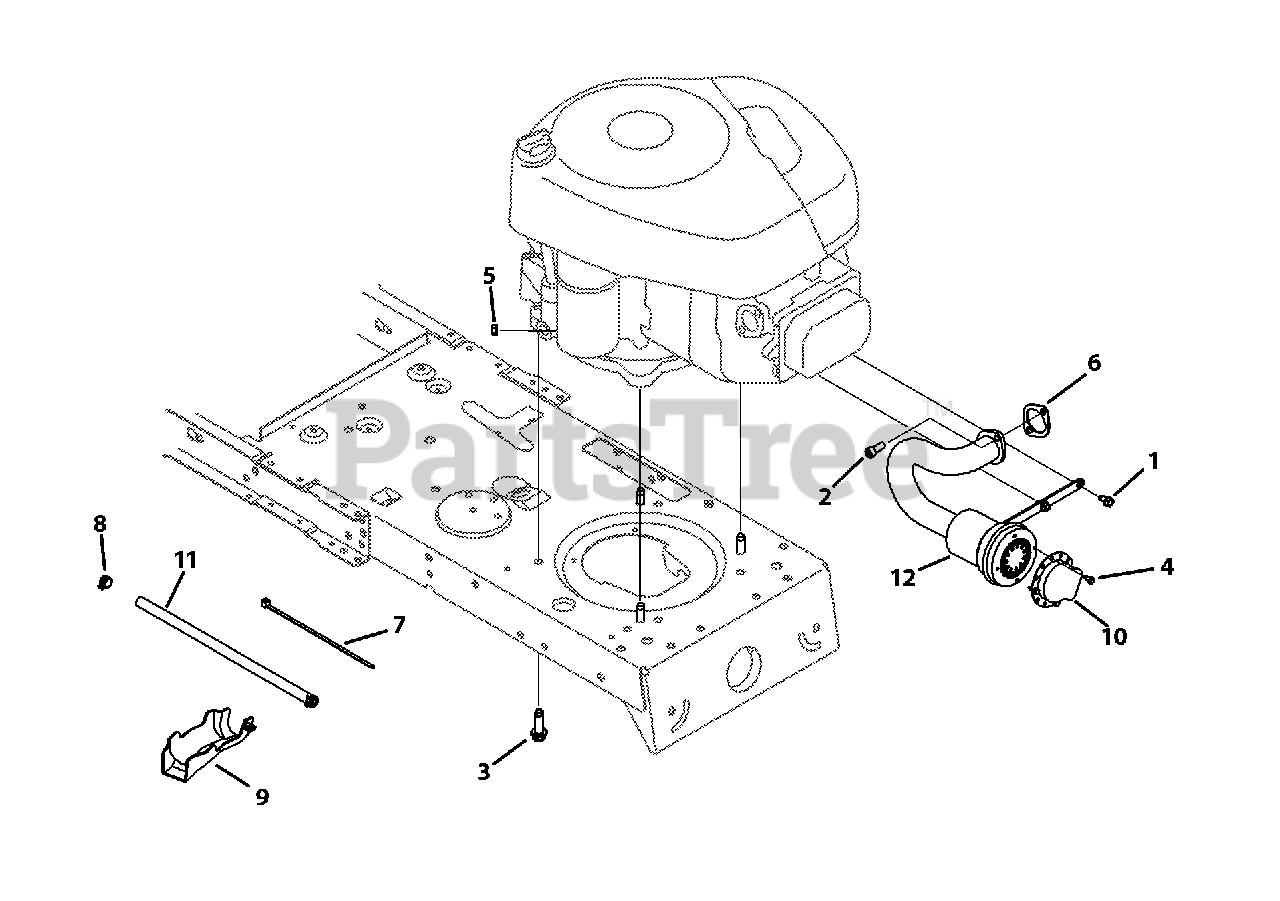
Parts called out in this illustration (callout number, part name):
1	Screw, 1/4-20 x .500
2	Socket Screw, 5/16-18 x .750
3	Screw, 3/8-16 x 1.0
4	Screw, 8-18 x .500
5	Sems Nut, 1/4-20
6	Exhaust Gasket, 10 HP Briggs
7	Cable Tie
8	Clamp Hose, .490 diameter
9	Oil Drain Sleeve
10	Muffler Deflector
11	Fuel Hose, Low Permeation
12	Muffler
